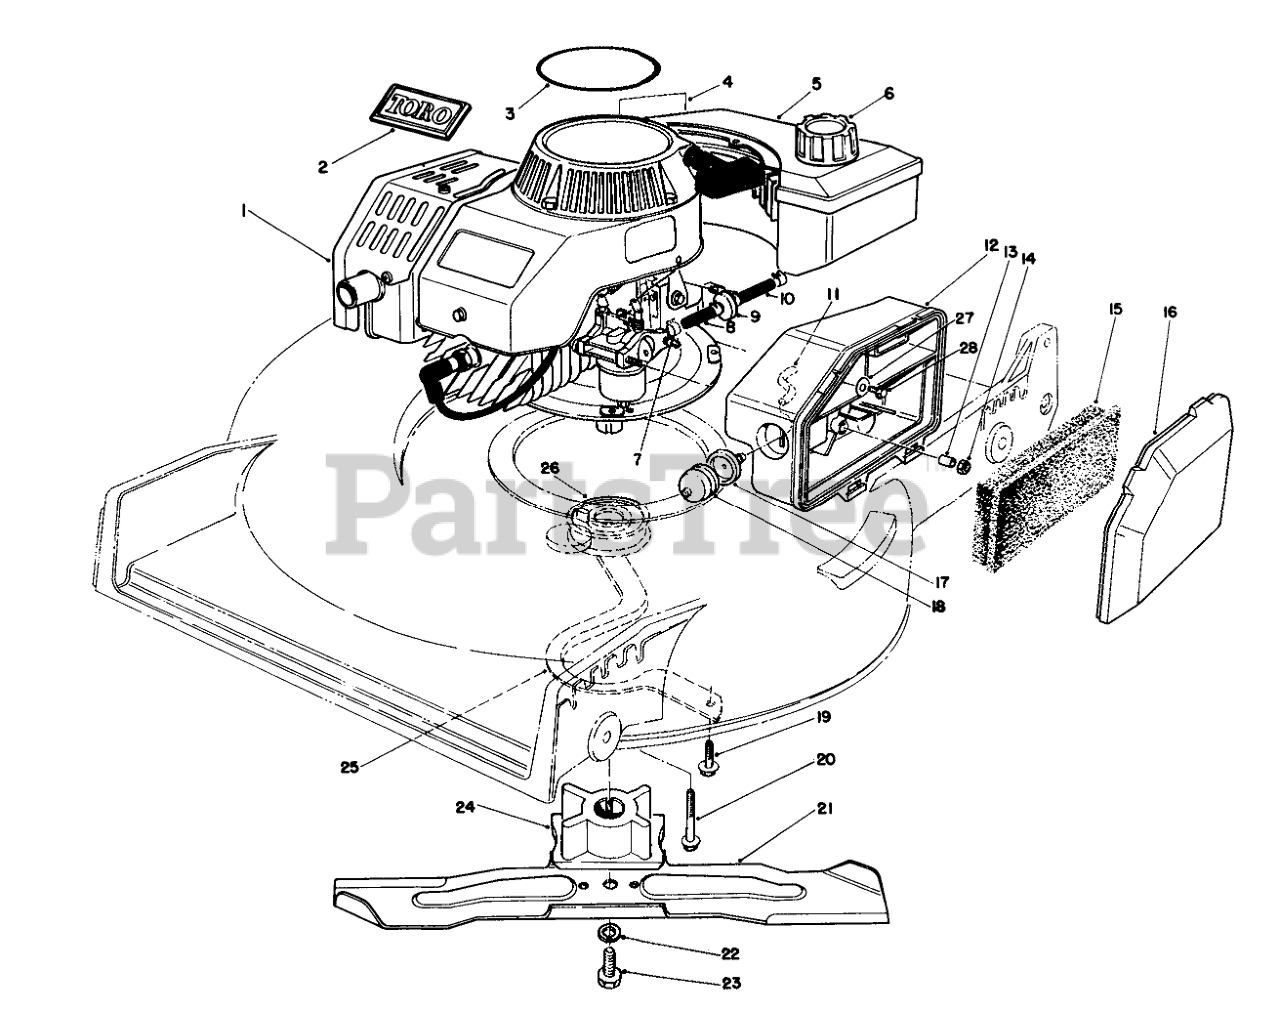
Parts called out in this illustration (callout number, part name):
1	Engine (Complete)
2	TORO LOGO PLT
3	DECAL- 2 CYC RECOIL
4	Decal-Maintenance
5	Gas Tank Assembly
6	GAS CAP ASM
7	CLAMP-FUEL LINE
8	HOSE-FUEL
9	FILTER-FUEL
10	HOSE-FUEL
11	HOSE-PRIMER
12	BODY-AIR CLEANER
13	SPACER
15	ELEMENT-AIR CLEANER
16	COVER-AIR CLEANER
17	BODY-PRIMER
18	Bulb Primer
19	Screw
20	SCREW-HHF
21	BLADE-21in
22	WASHER-LOCK
23	SCREW-BLADE
24	BLADE RETAINER
25	BELT GUIDE
26	PULLEY-DRIVE, ZONE START
27	WASHER-FLAT
28	SCREW-HH
